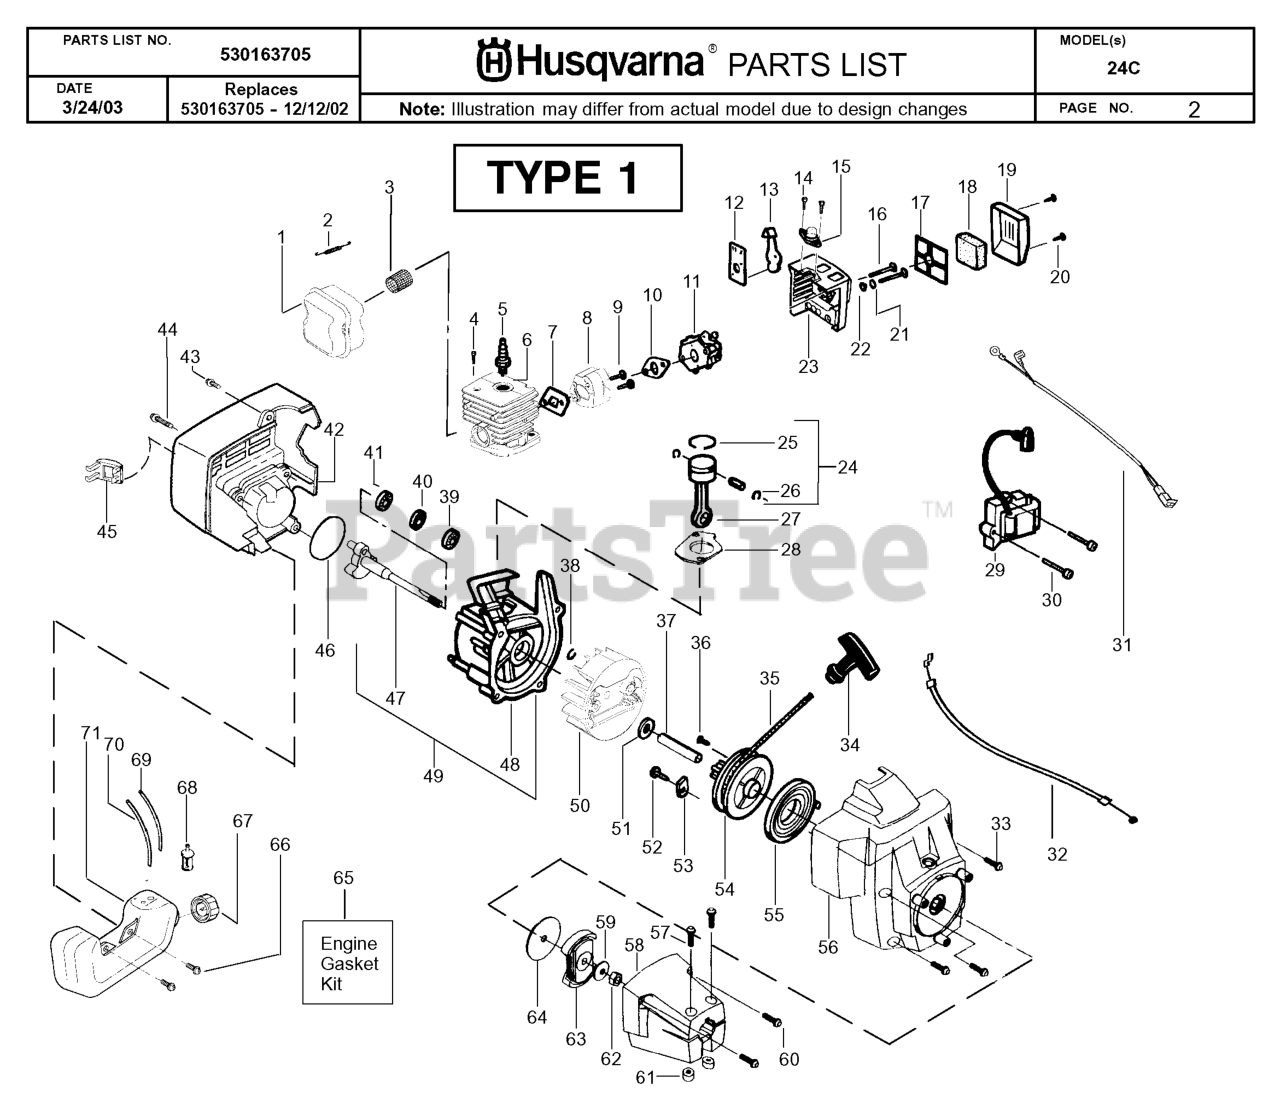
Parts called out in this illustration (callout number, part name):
1	KIT-MUFFLER
2	SPRING-MUFFLER (NEW STYLE)
6	CYLINDER
7	GASKET KIT
8	ASSY CARB ADAPTOR PHENOLRE
9	SCREW - CARB. ADAPTOR
10	GASKET KIT
11	CARBURETOR
12	CHOKE PLATE
13	CHOKE SHUTTER
14	SCREW 6-19X5/8 PLAS.PAN
15	AIR PURGE BUBBLE
17	FILTER PLATE
18	AIR FILTER FOAM
19	AIR FILTER COVER
20	SCREW FILTER PLATE
21	CHOKE SPACER
23	FILTER HOLDER
24	PISTON
25	PISTON RING
26	WRIST PIN RET.
27	KIT-CONN ROD ASSY
28	GASKET KIT
29	IGNITION MODULE
31	LEAD WIRE ASSEMBLY
32	THROTTLE WIRE
33	SCREW - SHROUD
34	STARTER HANDLE
38	RETAINING RING
39	OUTER BEARING
40	KIT-CRANKCASE SEAL
42	SHROUD HUSQ ORANGE
44	SCREW - SHROUD
46	GASKET KIT
47	ASSY-CRANKSHAFT
48	KIT ASSY CRANKCASE
49	KIT ASSY C'CASE/C'SHAFT
50	FLYWHEEL
52	SCREW 8-16 X 9/16 (PLAS
54	STARTER PULLEY KIT
55	STARTER SPRING
57	SCREW-10-24 X 1-3/8 (UN
58	ASSY CLUTCH HSG HUSKY
59	WASHER FLAT
60	SCREW-10-14 X 13/16 (PL
61	LOCKNUT-HEX 10-24
63	CLUTCH ASSEMBLY KIT
64	FRICTION DISC,CLUTCH 36/41
65	GASKET KIT
68	FUEL PICK-UP ASSY
69	KIT.LINE TANK/PURGE
70	HOSE. FUEL
